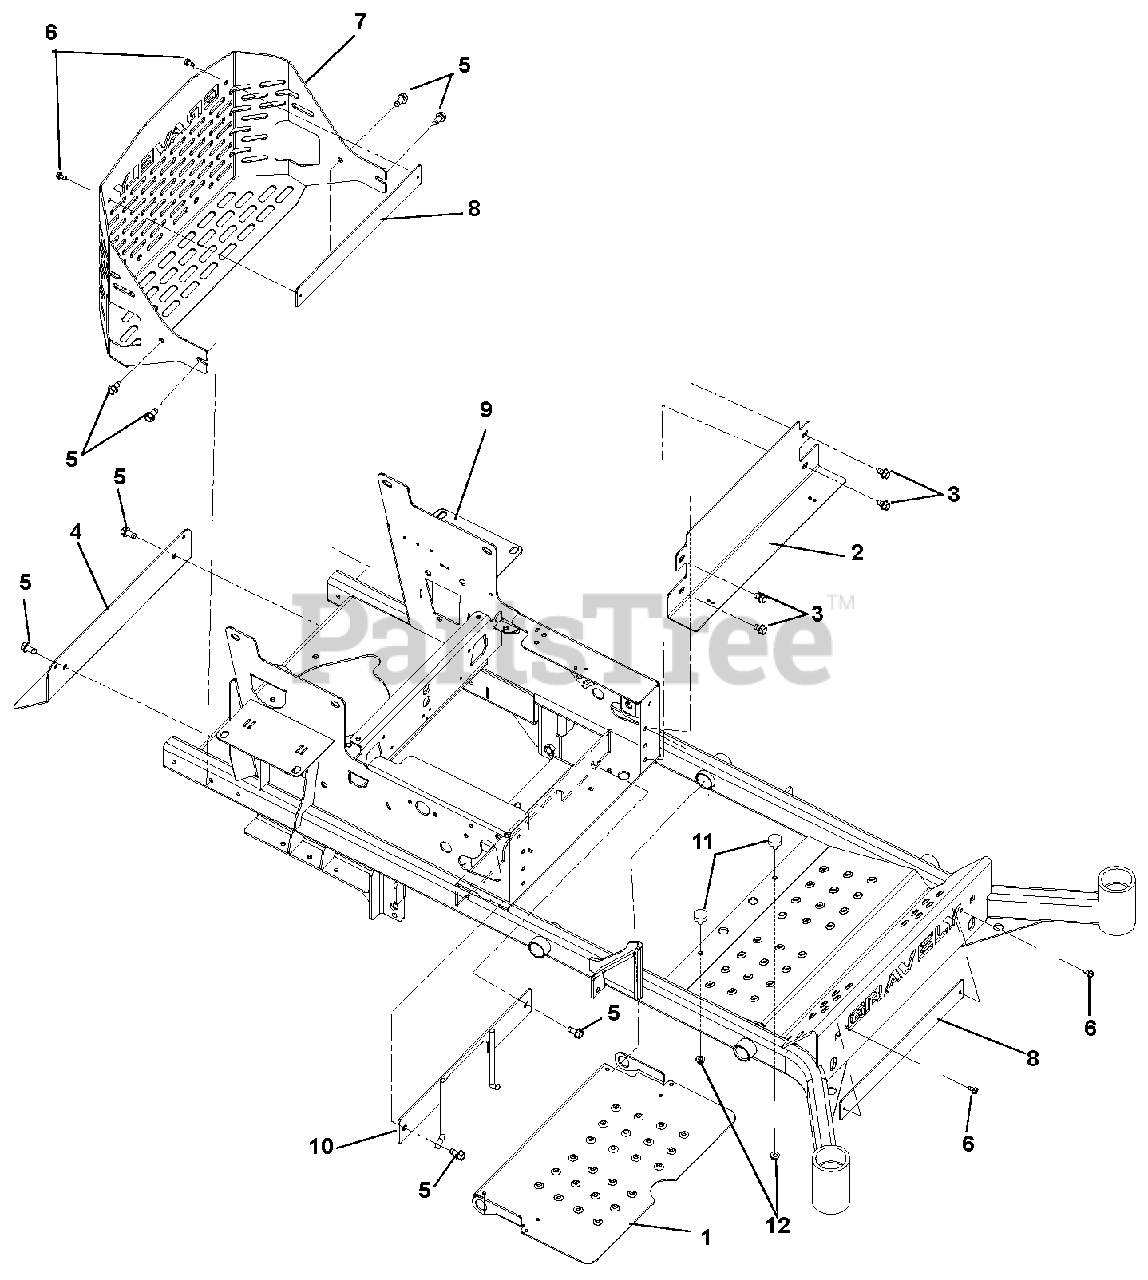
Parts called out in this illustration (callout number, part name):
1	Foot Plate
2	Kick Plate
3	Screw, Tapping .38-16 x .50 Hex Washer Head Thread Rolling
4	Muffler Heat Shield
5	Screw, Tapping .38-16 x .75 Hex Washer Head
6	Screw, Tapping .25-20 x .50 Hex Washer Head
7	Pro-Turn 100 Bumper
8	Bumper Plate
9	Pro-Turn 100 60" Main Frame Weldment (991081)
10	PTO Belt Finger Weldment
11	Bumper, Rubber
12	Nut, Spin Lock Flange .312-18
